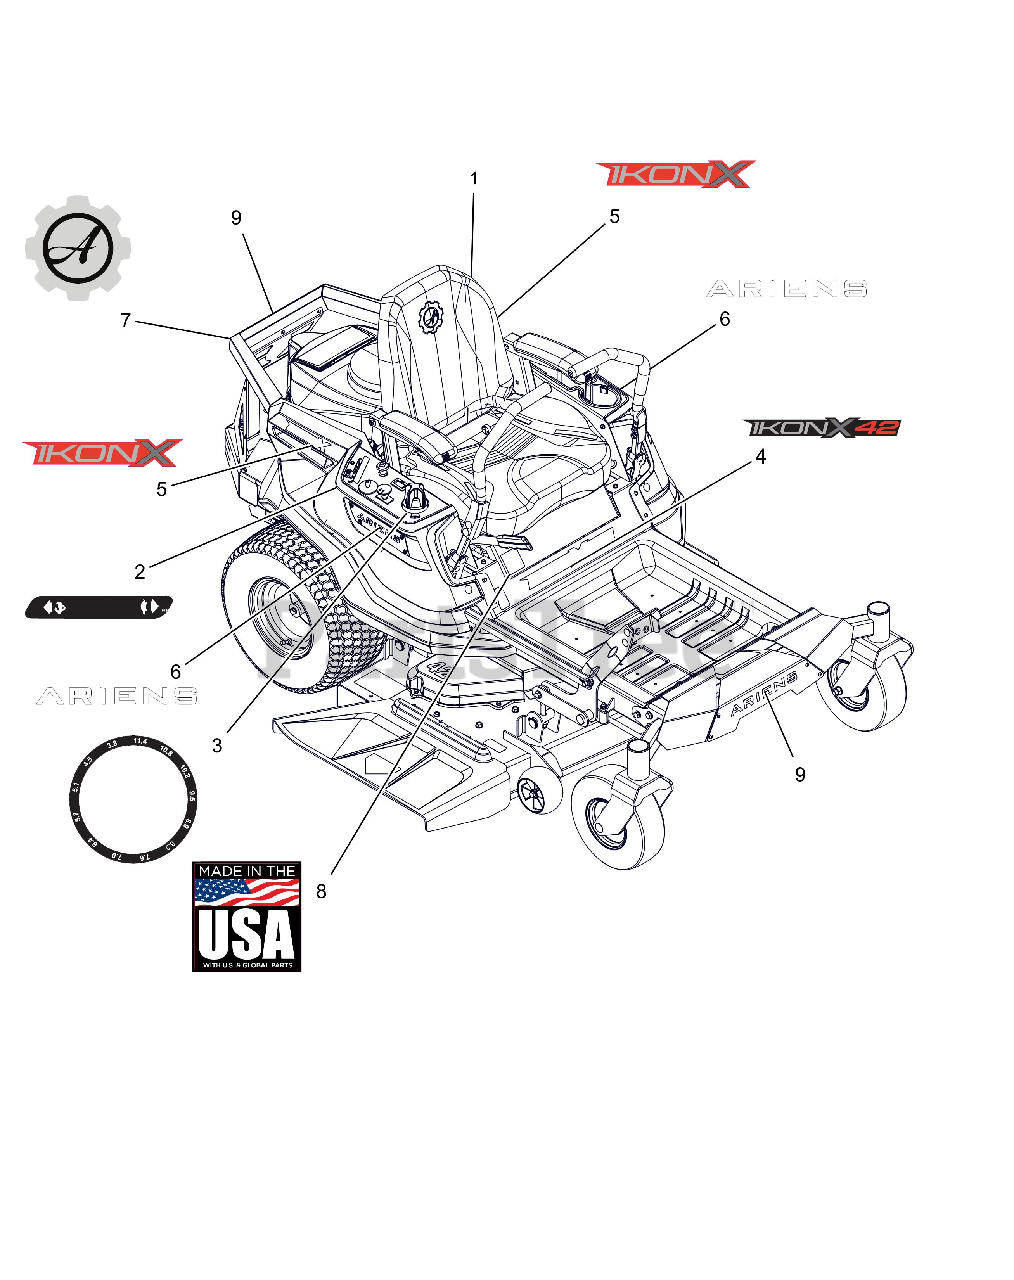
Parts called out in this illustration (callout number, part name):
1	DECAL, U1 BATTERY REPLACEMENT
2	DECAL, DASH DECAL
3	DECAL, CUT HEIGHT - IKON CE
4	DECAL, IKON-X 42"
5	DECAL, IKON
6	DECAL, ARIENS (6.50")
7	DECAL, ARIENS-GEAR BADGE
8	DECAL, MADE IN USA
9	DECAL - ARIENS 9.625"
